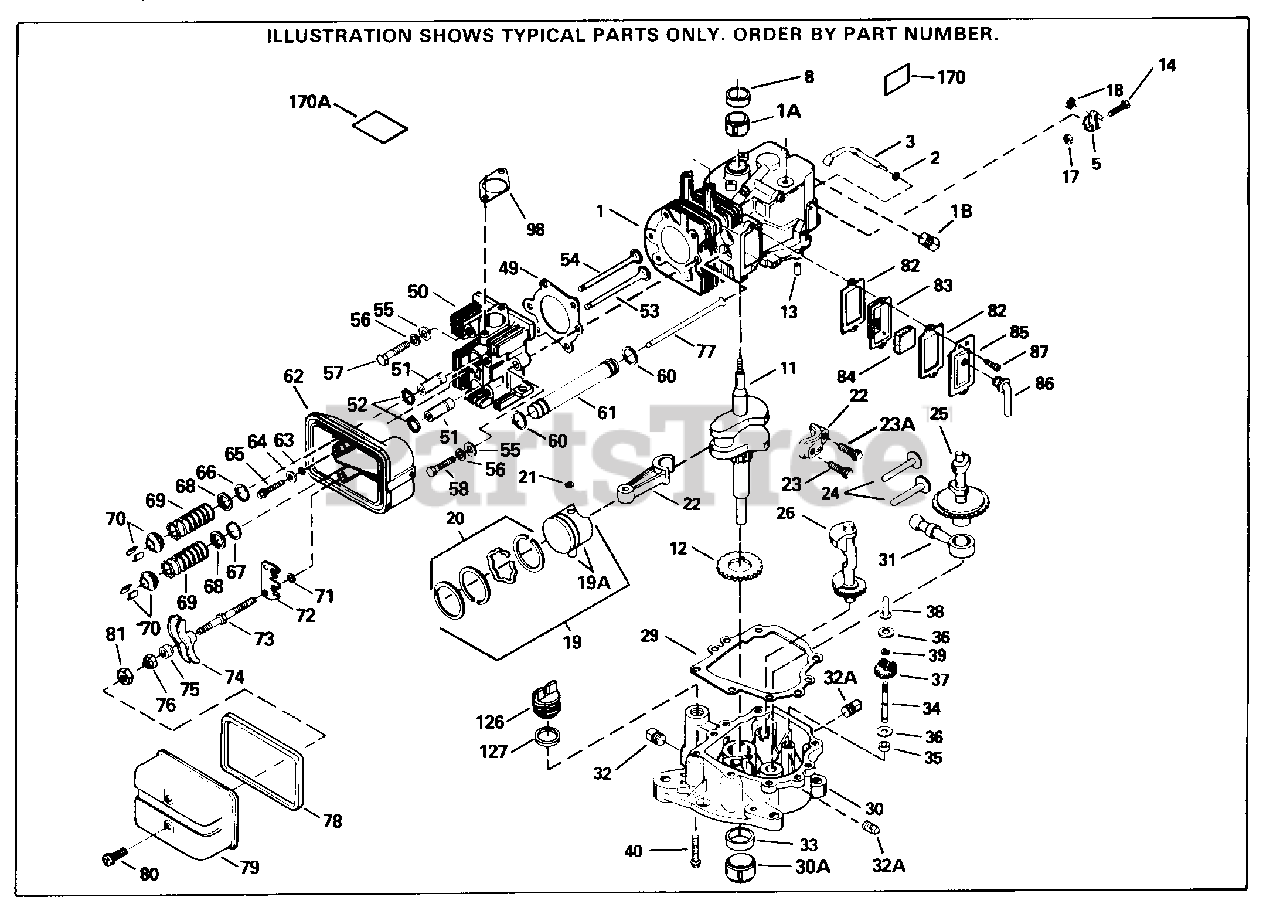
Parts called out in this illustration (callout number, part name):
1	"Cylinder (Incl. 1A,8,13)(3-5/16") CI liner
1A	Crankshaft Bushing
2	Flat Washer
3	Governor Rod
5	Governor Lever Clamp
8	Oil Seal
11	Crankshaft (Counterbalance)
12	Counterbalance Gear
13	Dowel Pin
14	Screw, 10-32 x 3/4"
17	Lock Nut, 10-32
18	Retaining Ring
19	Piston, Pin & Ring Set (Std.) 3-5/16" Bore
19	Piston, Pin & Ring Set (.010" OS)
19	Piston, Pin & Ring Set (.020" OS)
19A	Piston & Pin Ass'y. (Std.)(Incl. 21) 3-5/16"
19A	Piston & Pin Ass'y. (.010" OS) Incl. 21
19A	Piston & Pin Ass'y. (.020" OS) Incl. 21
20	Ring Set (Std.) (3-5/16" Bore)
20	Ring Set (.010" OS)
20	Ring Set (.020" OS)
21	Ring, Piston pin retaining
22	Connecting Rod Ass'y. (Incl. 46 & 47) )
23	Bolt, Connecting rod
23A	Bolt, Connecting rod
24	Valve Lifter
25	Camshaft (MCR)
26	Weight Assy., Counterbalance
29	Gasket, Mounting flange
30	Mounting Flange (Incl. 71,72,75 & 80) 34)
30A	Crankshaft Bushing
31	Pump Assy., Oil
32	Plug, Oil drain (3/8-18, Sq. hd.)
33	Oil Seal
34	Governor Shaft
35	Spacer, Governor Gear (Incl. 36)
36	WASHER
37	Governor Gear Assembly
38	Governor Spool
39	Retaining Ring
40	Screw, 1/4-20 x 1-3/16"
49	Gasket, Cylinder head
50	Cylinder Head
51	Valve Guide Kit (Incl. 2 of 52)
52	Ring, Retaining
53	Exhaust Valve (Std.)
53	Exhaust Valve (1/32" OS)
54	Intake Valve (Std.)
54	Intake Valve (1/32" OS)
55	Washer, Flat
56	Washer, Belleville
57	Screw, 5/16-18 x 1-3/8"
58	Screw, 5/16-18 x 1-3/4"
60	"O" Ring
61	Push Rod Tube
62	Rocker Arm Housing
63	"O" Ring
64	Washer, Flat
65	Screw, 1/4-20 x 29/32"
66	"O" Ring (Intake)
67	"O" Ring (Exhaust)
68	Cap, Valve spring
69	Spring, Valve
70	Cap, Valve spring keeper
71	"O" Ring
72	Push Rod Guide
73	Stud, Rocker arm housing
74	Rocker Arm
75	Rocker Arm Bearing
76	Nut Assy. (Incl. 81)
77	Push Rod
78	"O" Ring Ass'y. (Incl. 2 of 80)
79	Rocker Arm Housing
80	Screw, 8-32 x 1/2"
81	Nut, Hex Jam
82	Valve Cover Gasket
83	Breather Body
84	Breather Element
85	Valve Cover
86	Breather Tube
87	Screw, 10-24 x 1/2"
98	Gasket, Intake pipe
126	Oil Fill Plug (Incl. 312) also availa ble in Packaged Part #740079
127	Oil Fill Plug Gasket
170	Decal, Instruction
